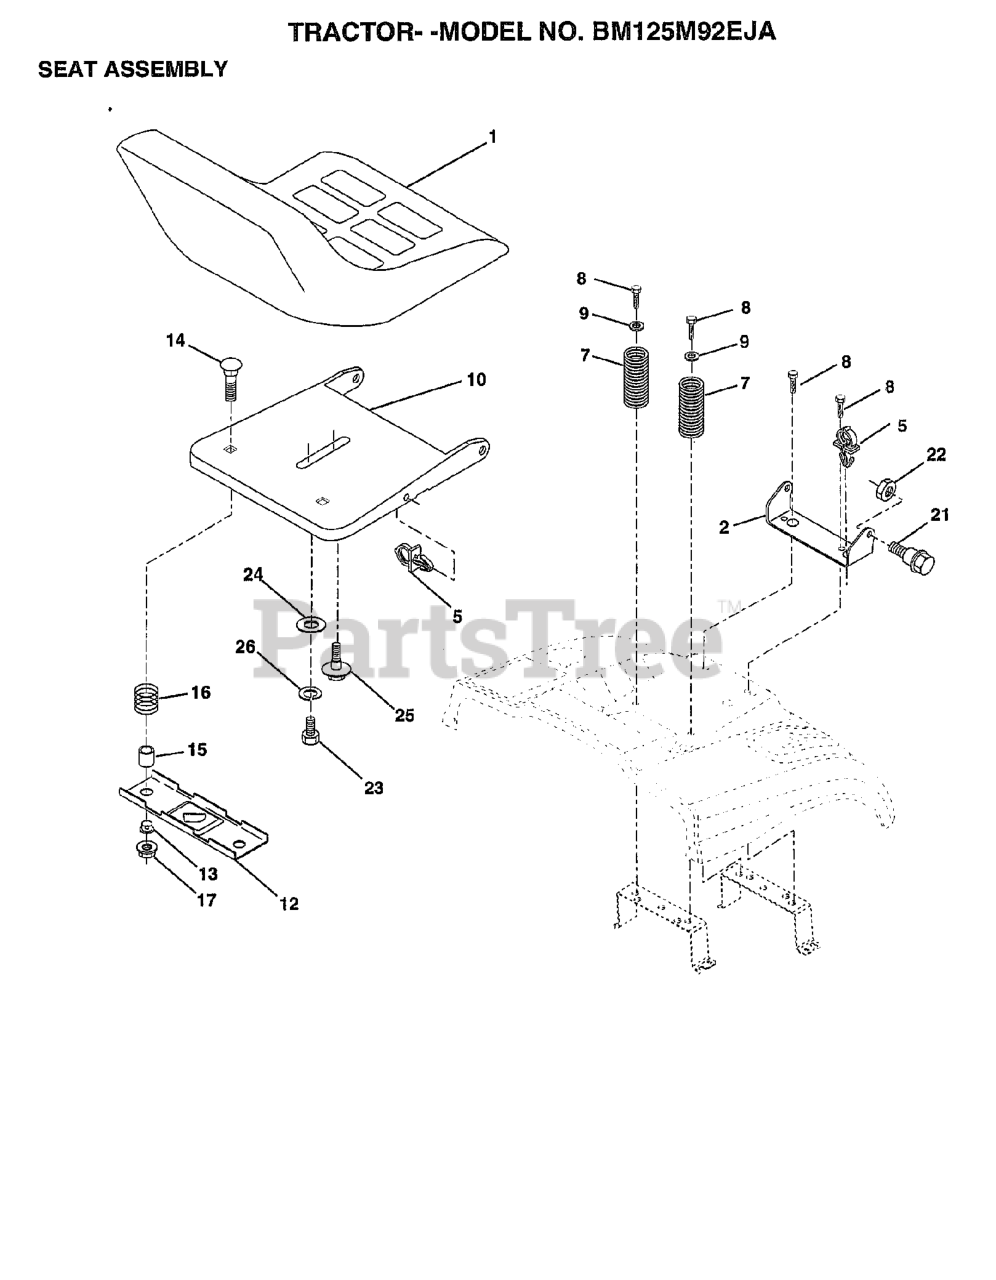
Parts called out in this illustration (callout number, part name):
1	SEAT
2	BRKT,SEAT PIVOT**
7	SPRING COMPRESSION
8	SCREW GTV
9	WASHER
10	PAN, SEAT
12	BRKT SWITCH
14	BOLT.ROUND.HEAD.SQUARE.NECK
15	SPACER SPLIT 28X.96
17	NUT T
21	BOLT SHOULDER 5/16-18
22	NUT.71038.31-18.HEX.NYLOCK
23	BOLT
25	BOLT, SHOULDER**
26	LOCKWASHER
